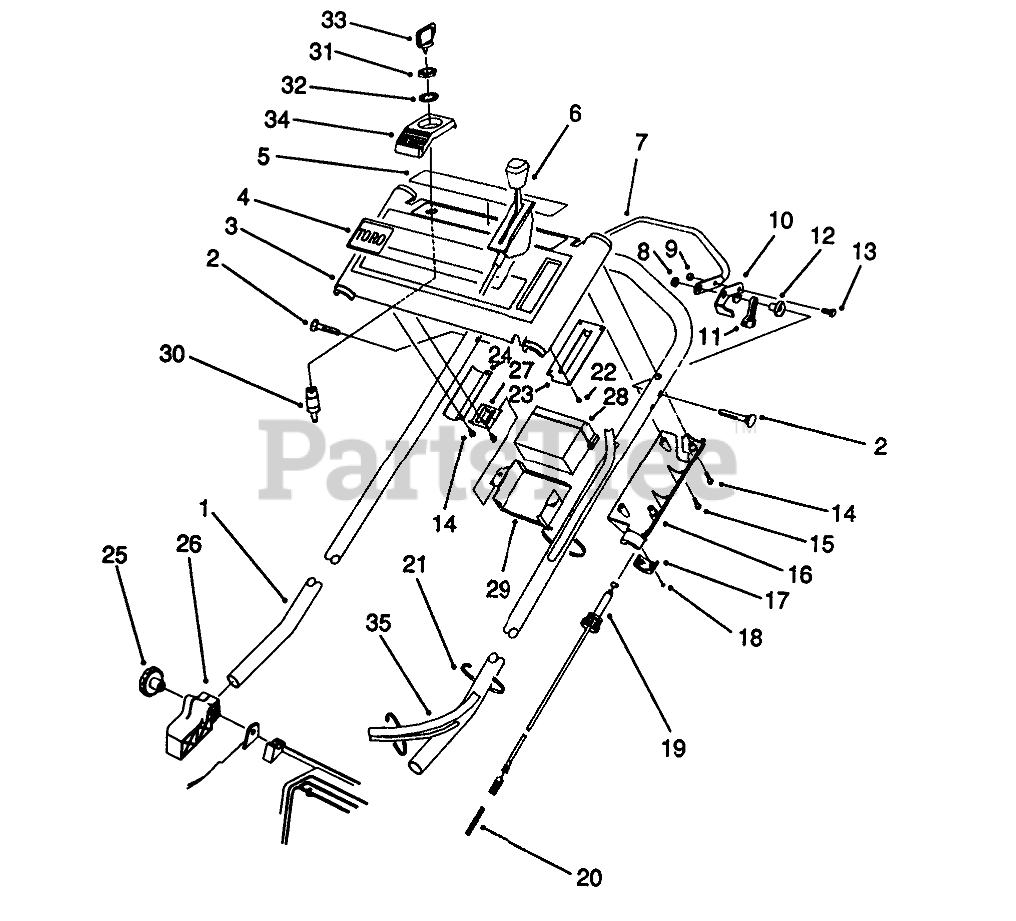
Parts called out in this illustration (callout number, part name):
1	Handle
2	SCREW-HANDLE
3	Panel-Control (Incl Ref. #4, & 5)
4	DECAL - TORO
5	DECAL - DANGER PANEL
6	THROTTLE CONTROL
7	CONTROL BAR
8	NUT-LOCK, NI
9	NUT-LOCK, NI
10	CONTROL LEVER
11	LEVER-TRACTION
12	SPACER-SUPPORT
13	SCREW-HH
14	SCREW-PPH, PLASTITE
15	Screw
16	Cover-Throttle Lower
17	LOWER THROTTLE CAP
18	#4-14X.62 PLASTITE SCW
19	TRACTION CABLE
20	SPRING-COMPRESSION
21	TIE-CABLE
22	#6-19X.25 PLASK FORM SC
23	THROTTLE PLATE
24	Bracket-Panel
26	MOUNT-HANDLE, RH
27	BATTERY BRACKET
28	Battery
29	BATTERY RETAINER
30	Switch-Starter (Incl. Ref. #31, & 32)
31	NUT-HH
32	WASHER-TOOTH, INTERNAL
33	KEY-IGNITION
34	IGNITION SWITCH BRACKET
35	WIRE HARNESS
